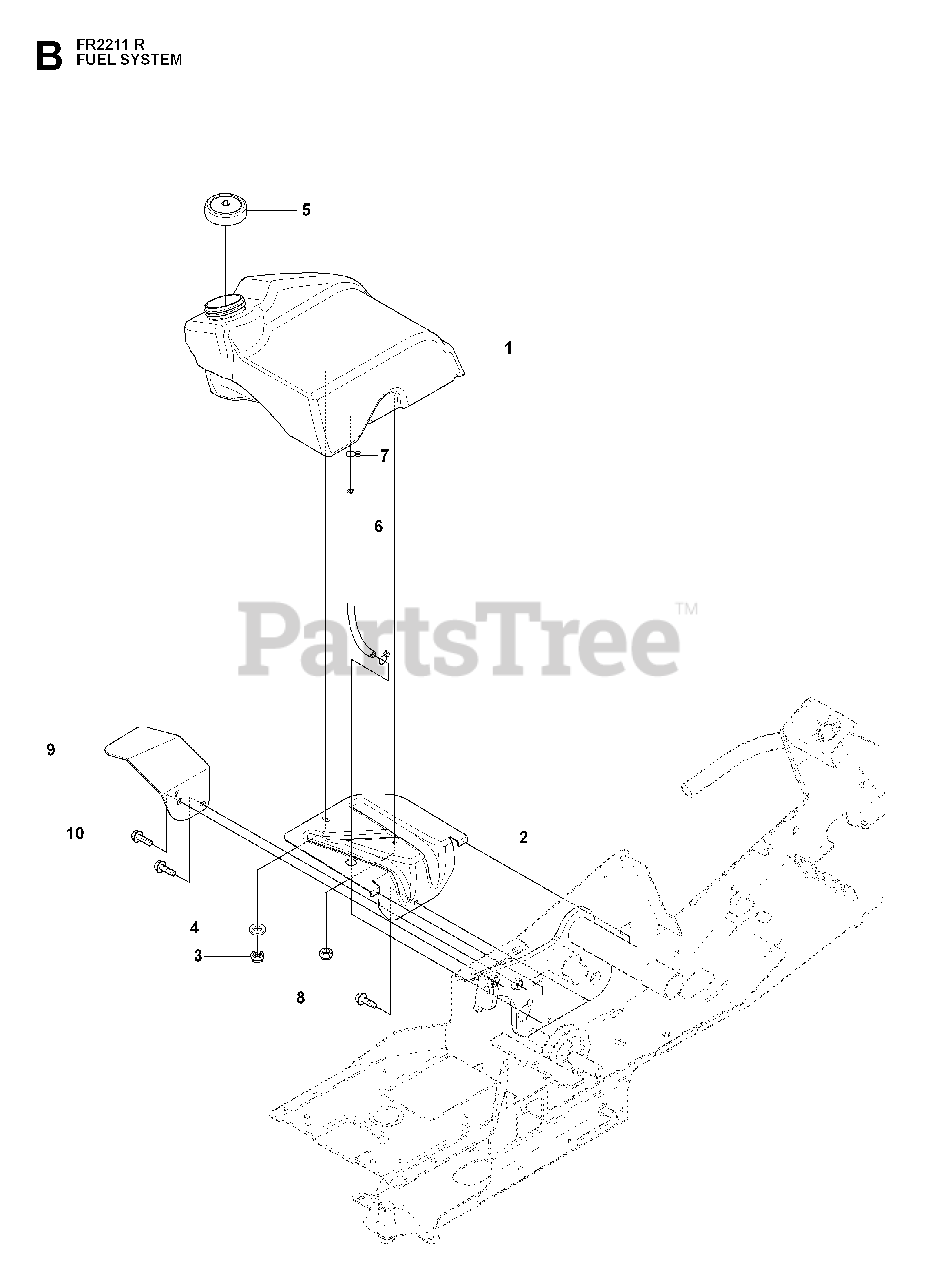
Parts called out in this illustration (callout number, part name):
3	LOCKNUT M6
4	WASHER
10	SCREW M10X25
